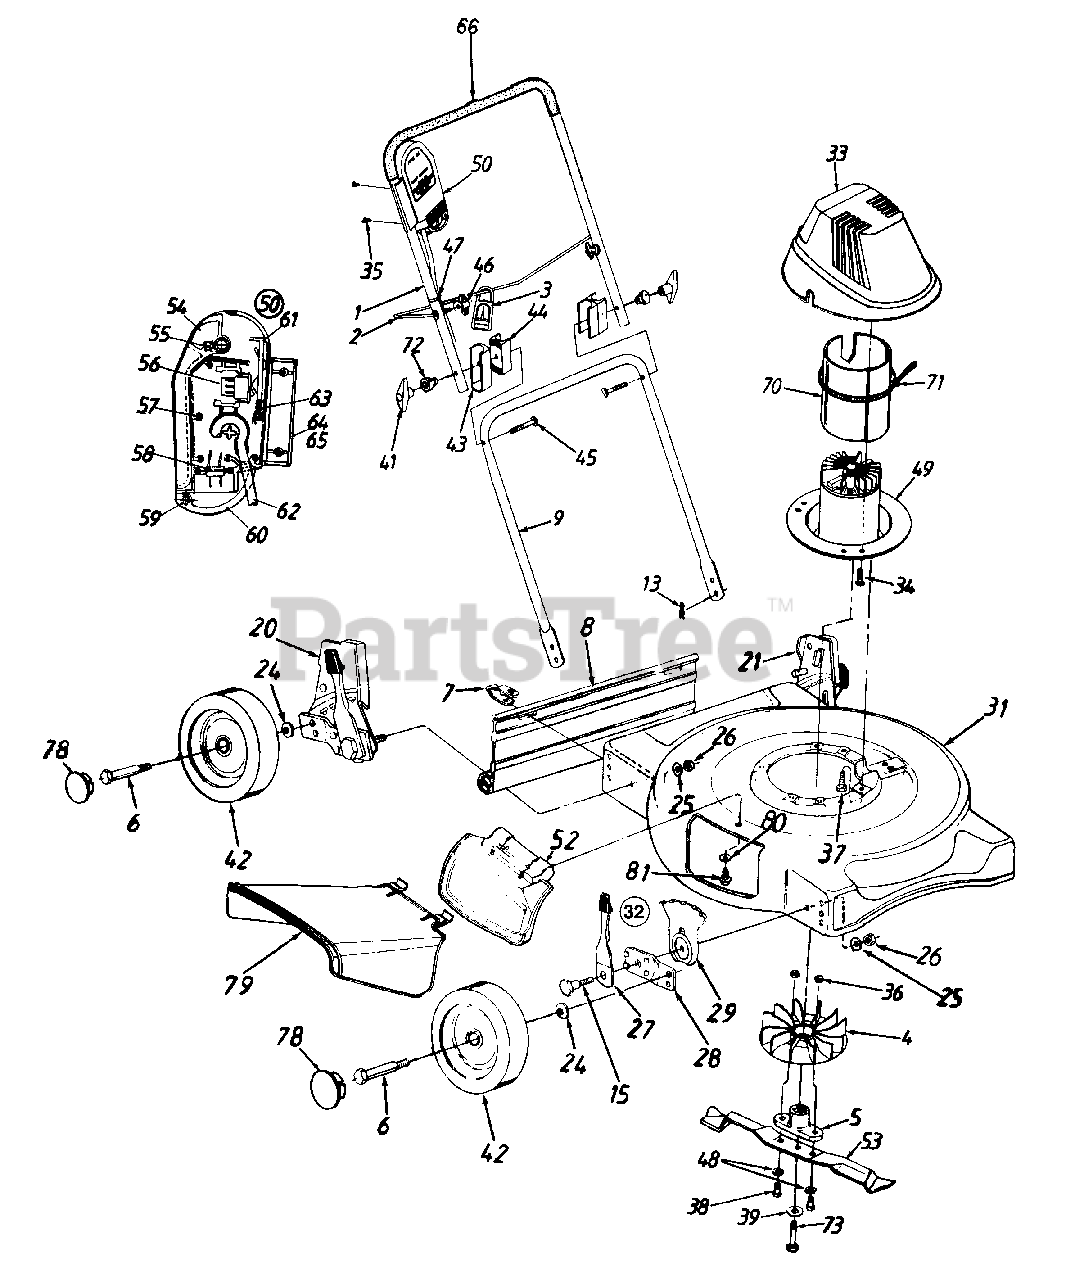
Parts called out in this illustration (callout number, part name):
3	Strain Relief-Cord
5	Blade Adapter
6	Axle Bolt
7	Hinge Clip
8	Rear Flap
15	Shld. Bolt .5" Dia. x .434"
24	Bell-Wash. .38" I.D. x .88" O.D.
25	Bell-Wash. .39" I.D. x 1.38" O.D.
26	Hex Nut 3/8-16 Thd.
27	Spring Lever Ass'y. w/Knob
29	Height Adj. Plate
33	Motor Cover
34	Scr. #10-16 x .75" Lg.
35	Self-Tap. Scr. #7 x 1" Lg.
36	Hex Nut 3/8-24 Thd.
37	Hex L-Wash. TT-Tap Scr. 3/8-16 x .75" Lg.
38	Hex Bolt 3/8-24 x 1.25" Lg.
39	Bell-Wash. .396" I.D. x 1.14"
41	Plastic Knob
42	Wheel Ass'y. Comp. (8" x 1.75")
43	Upper Handle Insulator
44	Lower Handle Insulator
45	Carriage Bolt 5/16-18 x 3" Lg.
46	Wing Nut 1/4-20 Thd.
47	Cable Tie
48	Bell-Wash. 3/8" I.D.
49	Motor, Cord & Switch Ass'y.
50	Cord & Switch Ass'y. Comp.
52	Mulching Plug
53	18" Blade
54	Handle-Switch Actuator
55	Spring-Switch Handle
56	Switch
57	Screw #6-32 x .5" Lg.
58	Plug Ass'y.
59	Retainer Plug Spring
60	Retainer Plug
61	Latch
62	Cord Ass'y.
63	Spring Latch
64	Housing-Upper Half
66	Foam Grip
70	Insulator
71	Cable Tie
72	Insulator Knob
73	Hex Bolt 3/8-24 x 2.5" Lg.
78	Hub Cap
79	Chute Deflector
80	Bell-Wash. 1/4" I.D.
81	Hex Wash. Hd. Tt-Tap Scr. 1/4-20 x .5" Lg.
